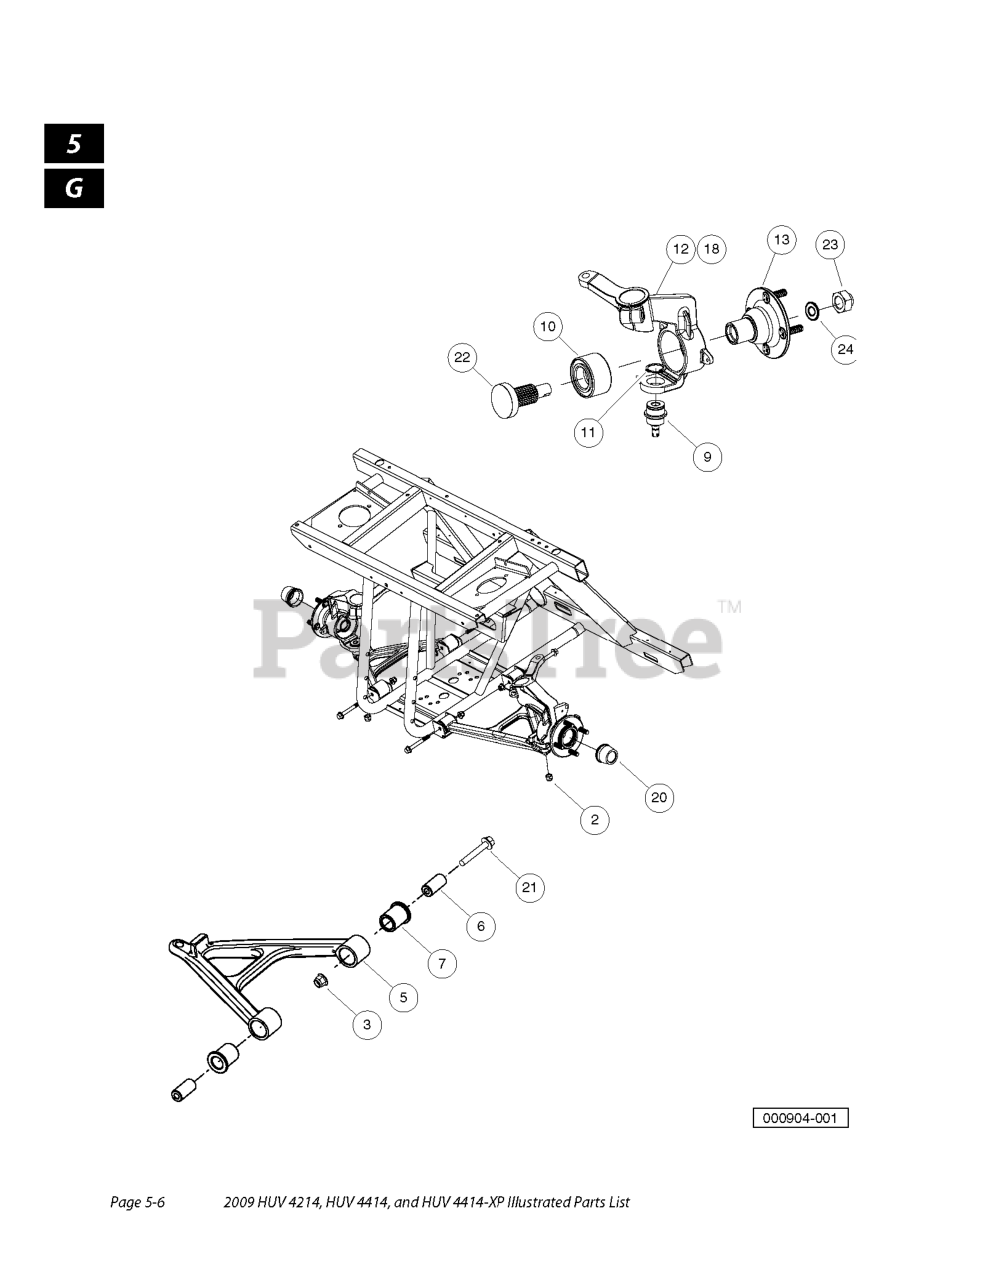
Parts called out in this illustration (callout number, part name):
2	LOCKNUT, M12-1.25 NYLON
3	NUT FLG M10 X 1.5 NYLON
4	ASM, A-ARM
7	BUSHING, LOWER ARM
8	ASM, UPRIGHT, RH
9	BALL JOINT
10	BEARING, DAC
11	RING, RETAINING, EXT, 1-1/4"
12	STRUT, RH, MACHINED
13	ASM, WHEEL HUB, FRONT
14	ASM, UPRIGHT, LH
15	BALL JOINT
16	BEARING, DAC
17	RING, RETAINING, EXT, 1-1/4"
19	ASM, WHEEL HUB, FRONT
20	CAP, WHEEL, RUBBER
21	BOLT, FLG, M10 X 1.5 X 80
23	NUT, STAKE, M18, HALFSHAFT
24	WASHER, FLAT, M18
